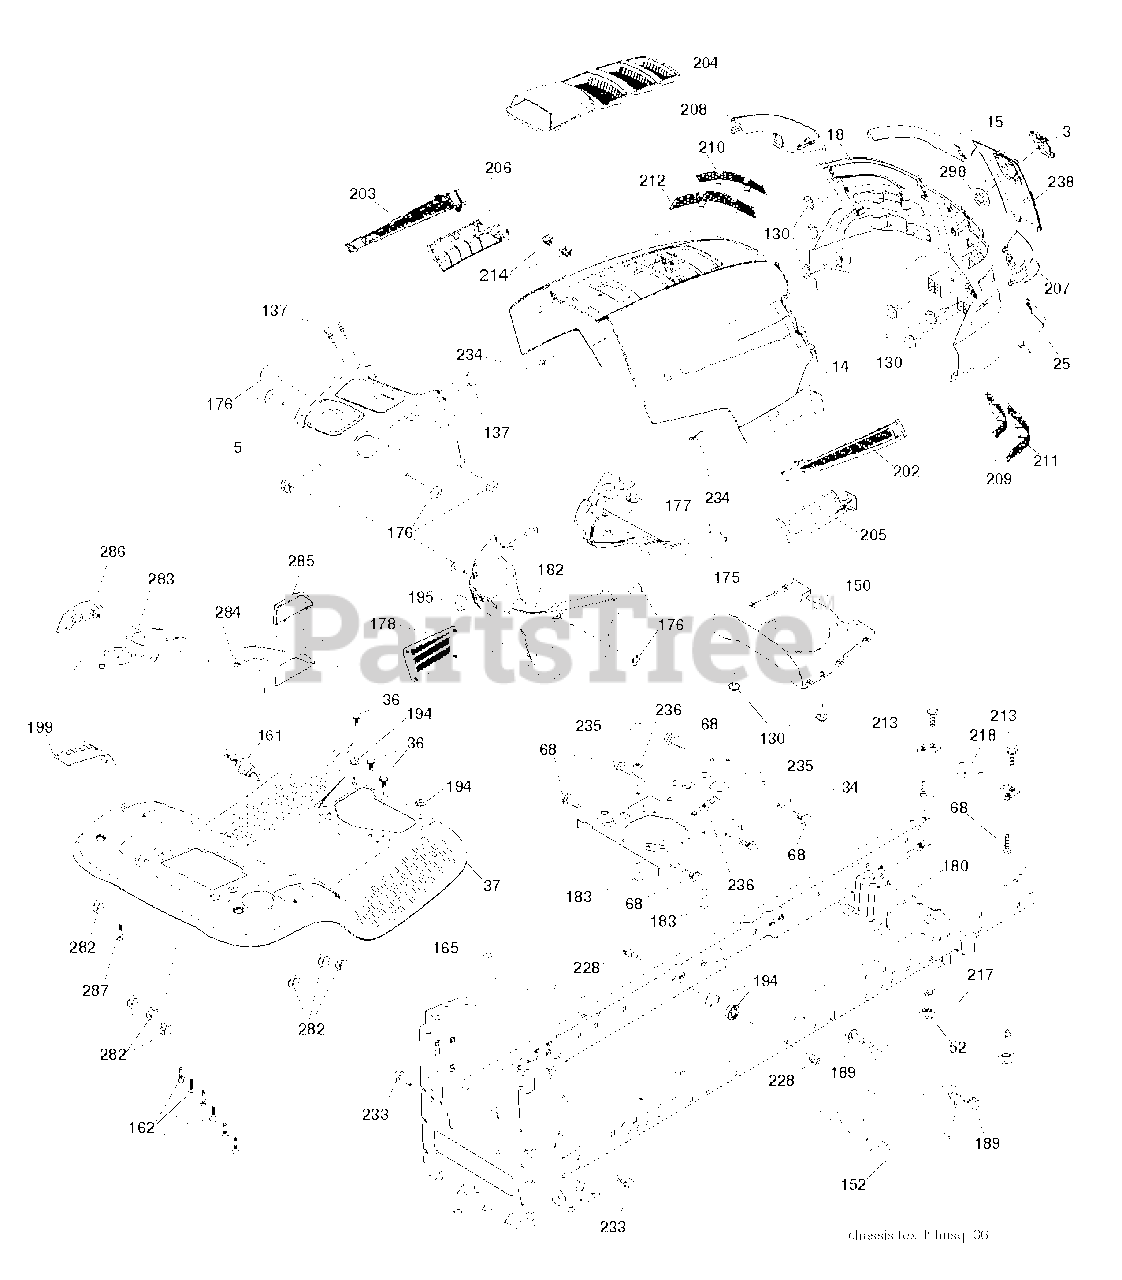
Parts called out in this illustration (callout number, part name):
3	RP LOGO
14	HOOD
15	LENS.LH.TEX.GT.HUSQ.CL
18	GRILL.ASM.HUSQ.TG/CRD.W/TRIM
25	LENS.RH.TEX.GT.HUSQ.CL
34	PLATE.ENGINE.WELDED.CHASSIS
36	SCREW 5/16"
37	FENDER.TLT.FS.W/CPH/FW/RSF.ORN
52	LOCKNUT
68	SCREW LT
130	SCREW.#10 X 0.750.BOS
137	BUMPER DASH
150	AIR.DUCT.HOOD.TEX.GT.HUSQ
152	SHIELD.BROWNING.W/TEX
161	WINDOW FUEL
162	SCREW.HI-LO.CONSOLE
165	SUPPORT.TANK.REAR.W/TEX
175	PLATE.CROSSMEMBER.HUSQ
176	SCREW.#10-24X5/8.RN.QU
177	BUSHING, STEERING
178	CARGO.ASM.NET.TXGT.W/C
180	CHASSIS
182	DASH.LOWER.COMMON.12V.ADAPTOR
183	BOLT.5/16-18X1-1/4 FULL.THREAD
189	SCREW
194	NUT LOCK HEX FLANGE 5/16-18
195	PLUG.HOLE.DASH.LOWER.12V.BLK
199	PLATE.DECK.LIFT.HUSQ.LT
202	VENT.SIDE.HOOD.RH.HUSQ
203	VENT,SIDE.HOOD.LH.HUSQ
204	HOOD VENT
205	HOOD SIDE SKIRT RH
206	SKIRT.HOOD.SIDE.HUSQ.L
207	BEZEL.RH.TEX.GT.HUSQ
208	BEZEL.LH.TEX.GT.HUSQ
209	INSERT.HEX.GRILL.HUSQ.GREY
210	INSERT.HEX.GRILL.HUSQ.
211	INSERT.HEX.GRILL.HUSQ.
212	INSERT.HEX.GRILL.HUSQ.
213	BOLT
214	CLIP.RETAINER.TINNER.
217	ROD.PIVOT.HOOD
218	X-PIECE.HOOD.STOP.NON/
228	STUD.FASTNER.W/ANTI-ROTATE
233	BOLT.SHOULDER
234	BUMPER.HOOD.TEX.HUSQVARNA
235	SPACER FENDER
236	NUT.CENTERLOCK.5/16-
238	TRIM.HUSQ.TG/CRD.SERVICE
282	CLIP.RETAINER.CONSOLE.LT.HUSQ
283	CONSOLE.DECK.LFT.R.SDFL.HUSQLT
284	CONSOLE.CNTRL.
285	CONSOLE INSERT RH
286	CONSOLE.INSRT.LH.HUSQ.LT.BLACK
287	SCREW 1/4X20
